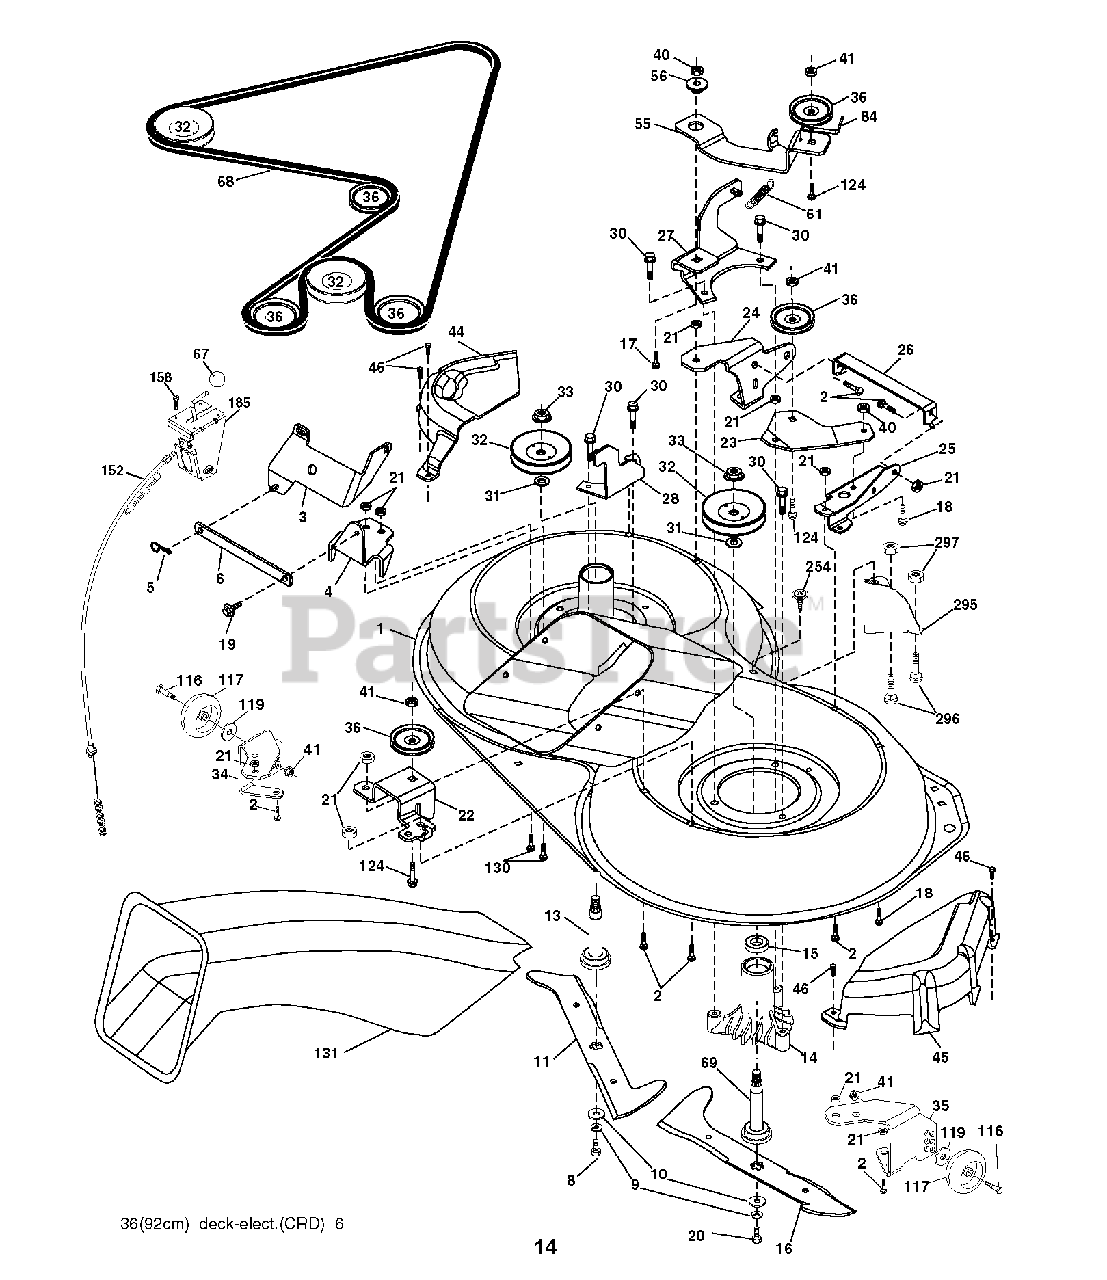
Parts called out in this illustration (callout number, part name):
2	BOLT
3	BRACKET
5	RETAINER-SPRNG RB
6	BAR SWAY
9	LOCKWASHER
10	WASHER.BLADE
13	SHAFT ASM VENT
14	HSG MANDREL
17	BOLT.3/8-14X1.25
19	BOLT SHD 5/16-18
21	LOCKNUT
24	BRACKET
25	BRACKET
28	BRACKET
30	SCREW, WASHER HEAD
31	WASHER.SPACER.MANDREL
32	PULLEY MANDREL
33	NUT.FLANGE.LOCK.TOP
36	PULLEY.IDLER.4.25
40	LOCKNUT
41	NUT LOCK FLG 3/8-16 UNC
45	MANDREL COVER
46	SCREW.1/4-20X5/8
56	SPACER.RETAINER.MOWER
67	KNOB T (3/8 HOLE)
69	SHAFT.ASM.W/LWR.BRG.RH.THREAD
84	KEEPER, BELT IDLER
116	BOLT.SHOULDER.3/8-16X3-5/8
117	WHEEL. GUAGE RALLY
124	BOLT.3/8-16X1.50
131	CHUTE BAGGER
158	SCREW
185	HEAD ASM. CABLE CLUTCH
254	SCREW 3/8-16X1
296	BOLT
297	NUT CENTERLOCK
